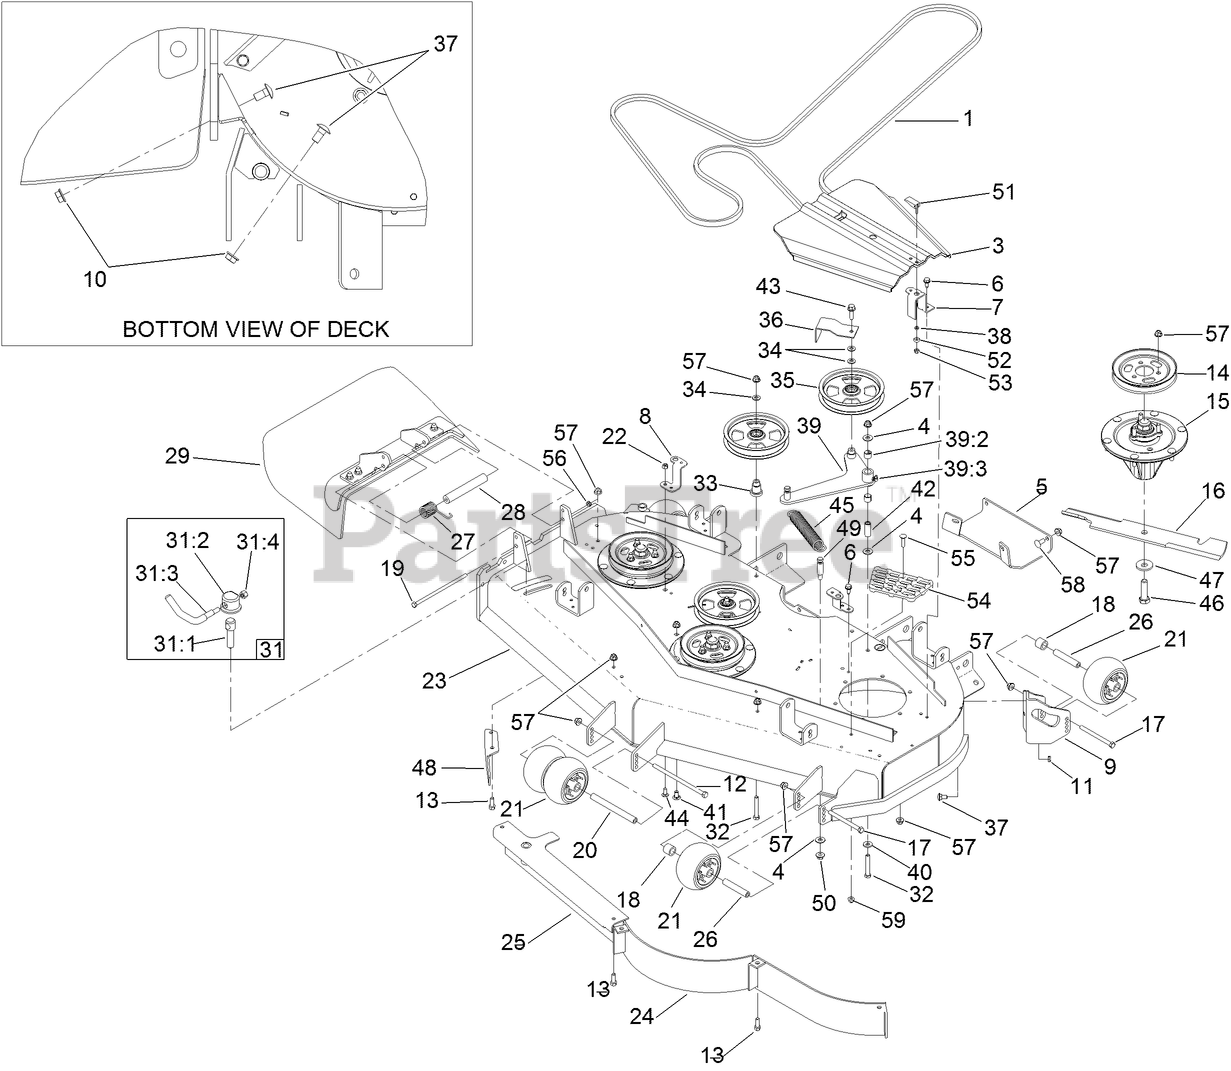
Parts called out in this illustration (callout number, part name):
1	BELT-V
3	COVER-BELT
4	WASHER-FLAT
5	PLATE-SKID
6	SCREW-HWHTF
7	BRACKET-COVER
8	BRACKET-COVER, TALL
9	MOUNT-WHEEL, LH
10	NUT-HHF, WHIZ
12	SCREW-HH
14	PULLEY
15	SPINDLE ASM
16	BLADE-18IN, HI FLOW
17	SCREW-HH
18	TUBE-SPACER
19	SCREW-HH
20	SPACER-WHEEL
21	ROLLER-SCALP, ANTI
22	NUT-LOCK, NI
23	DECK DECAL ASM
26	TUBE-SPANNER
27	SPRING-TORSION
28	SPACER
29	RUBBER DEFLECTOR ASM
31	LEVER ASM
31:1	SCREW-LOCK
31:2	CAP-LOCK
31:4	NUT-LOCK, NI
32	SCREW-HH
33	MOUNT-PULLEY
34	WASHER-FLAT
35	PULLEY-IDLER, FLAT
36	GUIDE-BELT
37	SCREW-HH
38	WASHER
39	DECK IDLER ARM ASM
39:2	SLEEVE-BEARING
39:3	FITTING-GREASE, 90 DEG
40	WASHER-BELLEVILLE
41	SCREW-CARR
42	BUSHING
43	SCREW-HHF
44	SCREW-CARR
45	SPRING-EXTENSION
46	SCREW-BLADE
47	WASHER-BLADE BOLT, HEAVY
48	BAFFLE-DISCHARGE
49	PIN-THREADED, SPRING ANCHOR
50	NUT-HF
51	HANDLE-LATCH, SWELL
52	BUSHING-LATCH, SWELL
53	NUT-LOCK, HH
54	STEP-DECK
55	SCREW-CARR
56	NUT-LOCK, NI
57	NUT-HF, NI
58	SCREW-CARR
59	NUT-HF, NI
